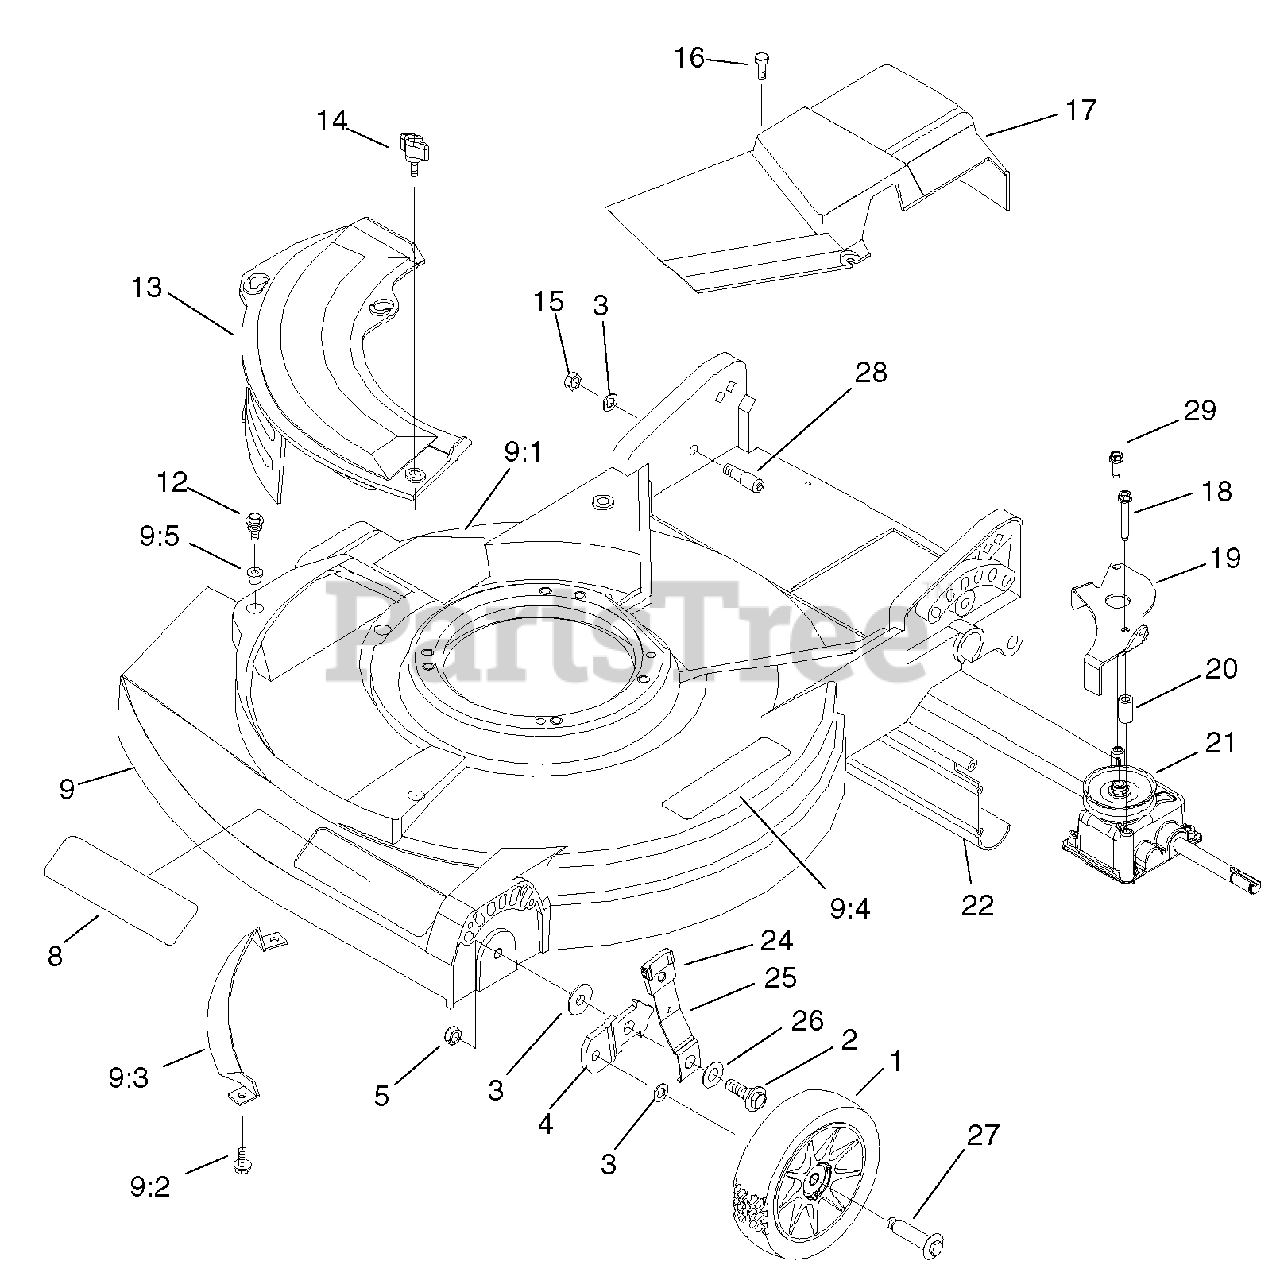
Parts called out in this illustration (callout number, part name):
1	WHEEL & TIRE ASM
2	BOLT-SHOULDER
4	BRACKET-HEIGHT ADJUSTMENT, WHEEL
5	NUT-LOCK, NI
8	DECAL-DECK
9:1	DECAL-DANGER
9:2	SCREW-HWH
9:3	BAR-TOE
9:4	DECAL-WARNING
9:5	GROMMET - PLASTIC
12	SCREW-SEMS
13	PLATE-MULCH
17	COVER-DRIVE
18	SCREW-HWHTF
19	BRACKET-TRANSMISSION
20	BUSHING-PLATE, ACTUATOR
21	GEAR CASE ASM
22	SHIELD - TRAILING
24	KNOB-LEVER, HEIGHT ADJUSTMENT
25	FRONT SPRING ARM ASM
26	WASHER-BELLEVILLE
27	BOLT-SHOULDER
28	SCREW-TORX
29	SCREW-TAPPING
